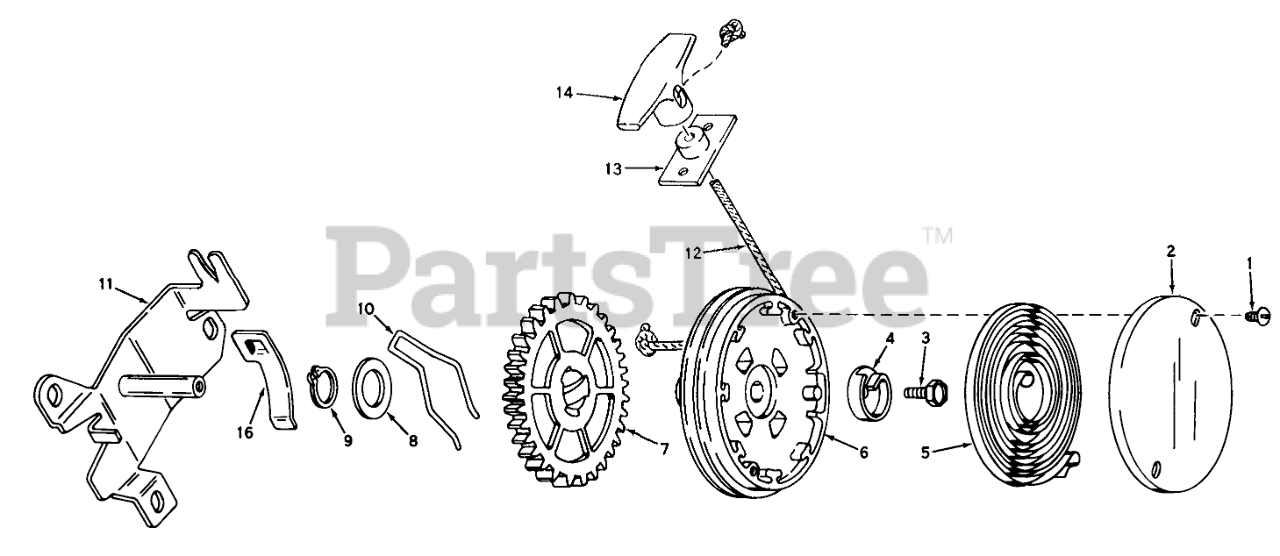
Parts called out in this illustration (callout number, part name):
1	Screw, Cover
2	Cover, Spring
3	Screw
4	Hub Spring
5	Spring, Rewind
6	Pulley
8	Washer
9	Ring, Snap
10	Brake
11	Bracket Assy., Mounting
12	Rope, Starter
13	Bracket Assy.
14	Handle-Starter
16	Clip Rope
